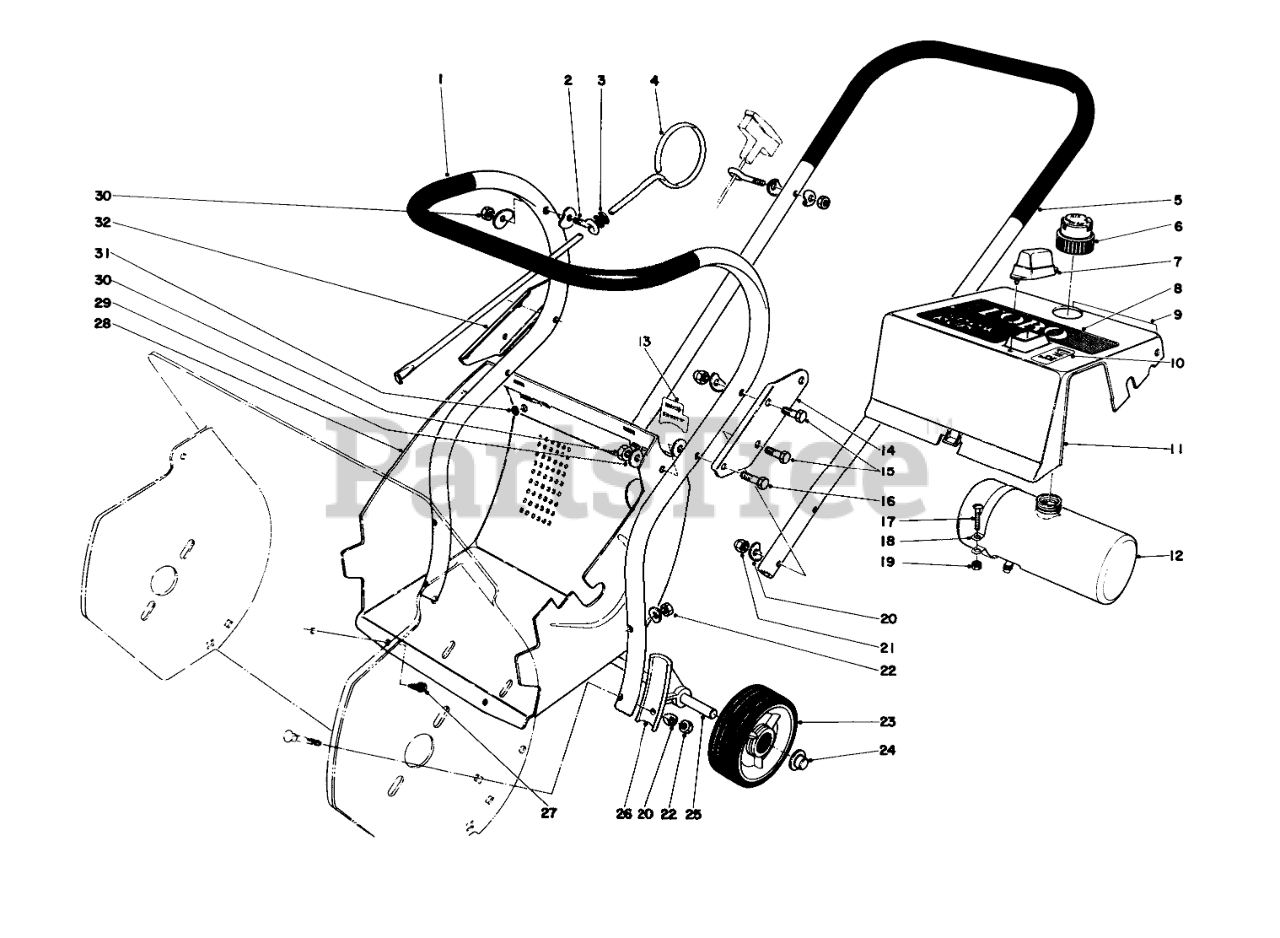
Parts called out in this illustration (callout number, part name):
1	Lower Handle
2	Bolt-Eye
3	GROMMET
4	Vane Adj. Rod
5	Upper Handle
6	Cap, Gas
8	Decal
9	Decal
10	Decal
11	Shroud, Upper (Incl. Ref. #7-10)
12	Gas Tank Assembly (Incl. Ref. # 6)
13	Decal
14	SPLICE PLATE
15	SCREW-HH
16	SCREW-HH
17	10-24 X 1 RND HD MS
18	1/2 GAS TANK CLAMP
19	NUT-SQ
20	WASHER
21	NUT-CAP
22	NUT-HEX
23	Wheel
24	RETAINER-PUSH ON
26	Wheel Bracket
27	SCREW-HWHTF
28	Lower Shroud (Incl. Ref. #31)
29	WASHER-FLAT
30	NUT-LOCK
31	SNO PUP PLATED EYELET
32	Plate-Splice
